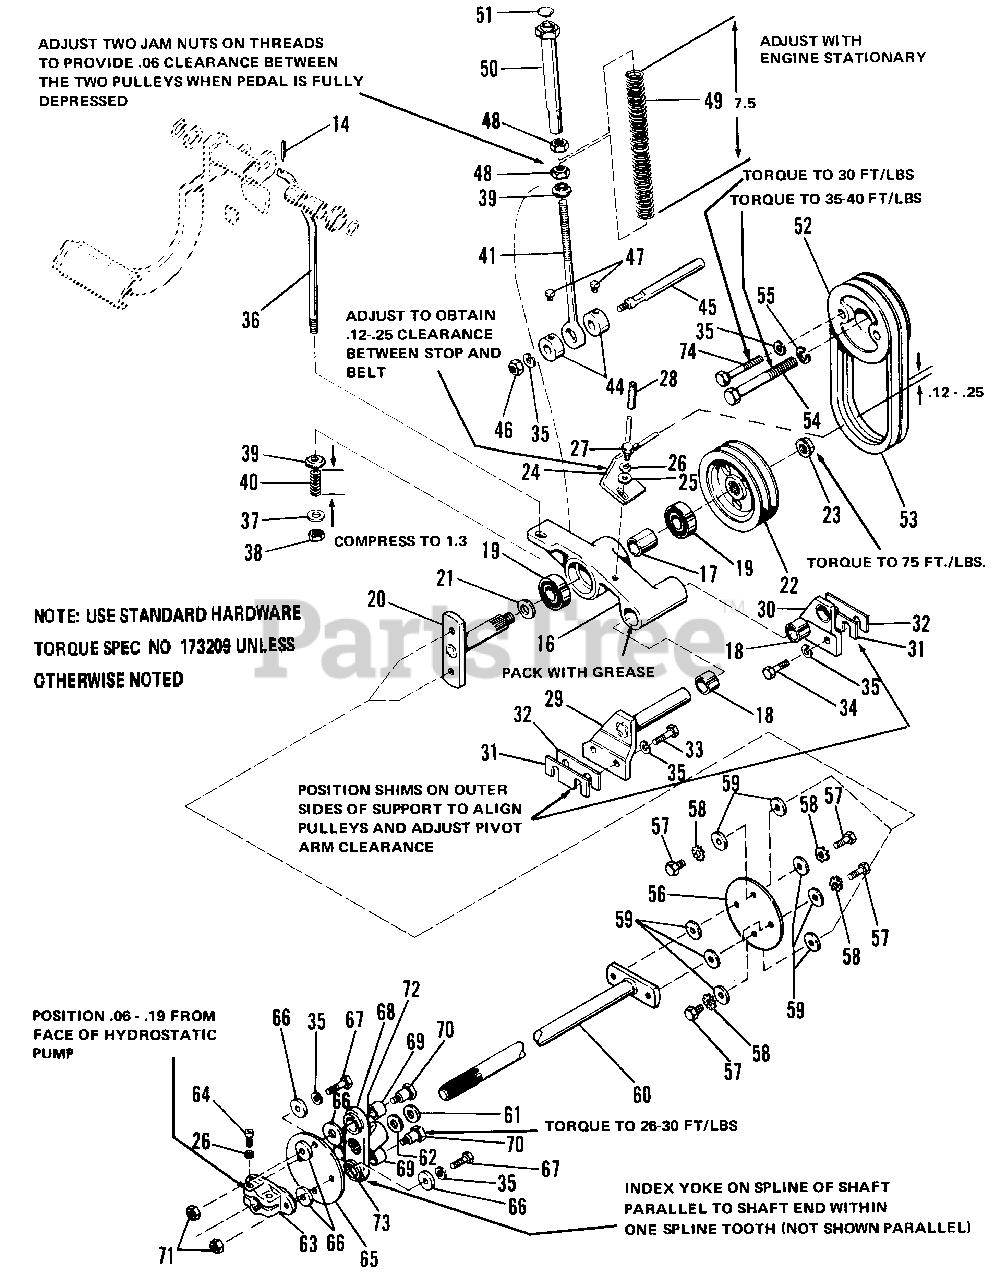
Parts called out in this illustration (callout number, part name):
14	PIN, Cotter, 3/32 x 3/4
16	ARM, Pivot
19	BEARING, Ball
22	PULLEY, Input
23	LOCKNUT, Hex, Flange, 1/2-13
24	STOP ASSY, Belt
25	WASHER, Plain, 5/16
26	LOCKWASHER, 5/16
27	CAPSCREW, Hex, 5/16-18 x 3/4
29	SUPPORT ASSY
30	SUPPORT ASSY
33	CAPSCREW, Hex, 3/8-16 x 1-1/2
34	CAPSCREW, Hex, 3/8-16 x 1-1/4
35	LOCKWASHER, 3/8
36	ROD, Clutch
37	WASHER, 3/8
38	NUT, Hex, Lock, 3/8-16
39	SPACER, Clutch
41	BOLT, Eye
44	COLLAR, Set
45	SHAFT, Pivot
46	NUT, Hex, 3/8-16
47	SCREW, Set, 5/16-18 x 5/6
48	NUT, Hex, Jam, 3/8-16
50	TUBE ASSY
52	PULLEY, Input
53	"V" BELT, Set of 2
54	CAPSCREW, Hex, 7/16-14 x 4-1/2
55	LOCKWASHER, 7/16
57	CAPSCREW, Hex, 3/8-16 x 3/4
58	LOCKWASHER, External Tooth, 3/8
60	SHAFT ASSY
61	WASHER, Rubber
62	WASHER, Felt
63	CLAMP, Yoke
64	CAPSCREW, Hex, Skt. Hd., 5/16-18 x 1-1/4
67	CAPSCREW, Hex, 3/8-16 x 1
70	BOLT, Shoulder
71	NUT, Hex, Whiz Lock, 3/8-16
72	FITTING, Lube, 1/4-28
74	CAPSCREW, Hex, 3/8-16 x 2-1/2
